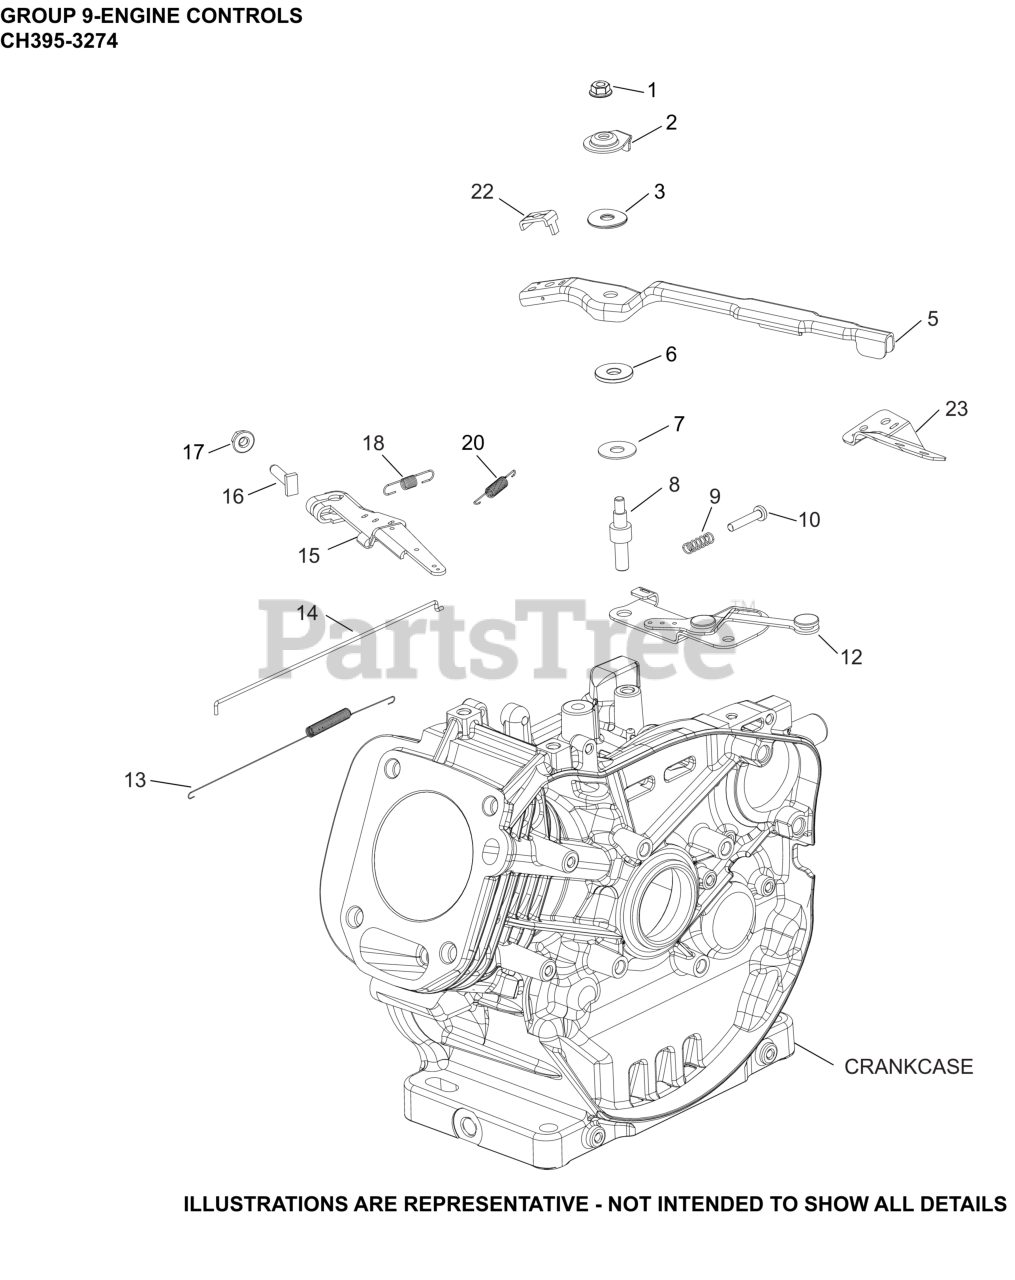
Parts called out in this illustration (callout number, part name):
1	NUT, HEX FLANGE LOCK (M6)
2	WASHER, CONTROL LEVER
3	WASHER, SPRING
5	CONTROL LEVER ASSEMBLY
6	WASHER, NYLON CONTROL LEVER
7	WASHER, FLAT
8	STUD, CONTROL LEVER
9	SPRING, COMPRESSION
10	SCREW, SPEED ADJUSTING
12	BRACKET, CONTROLS ASSY
13	SPRING, LINKAGE
14	LINKAGE, GOVERNOR
15	KIT, GOVERNOR LEVER
16	SCREW, RECTANGLE HEAD (M6)
17	NUT, HEX FLANGE (M6) - USE 14 100 16-S
18	SPRING, GOVERNOR
20	SPRING, THROTTLE RETURN
22	CLAMP, CABLE
23	BRACKET, BOWDEN CABLE ASSY
